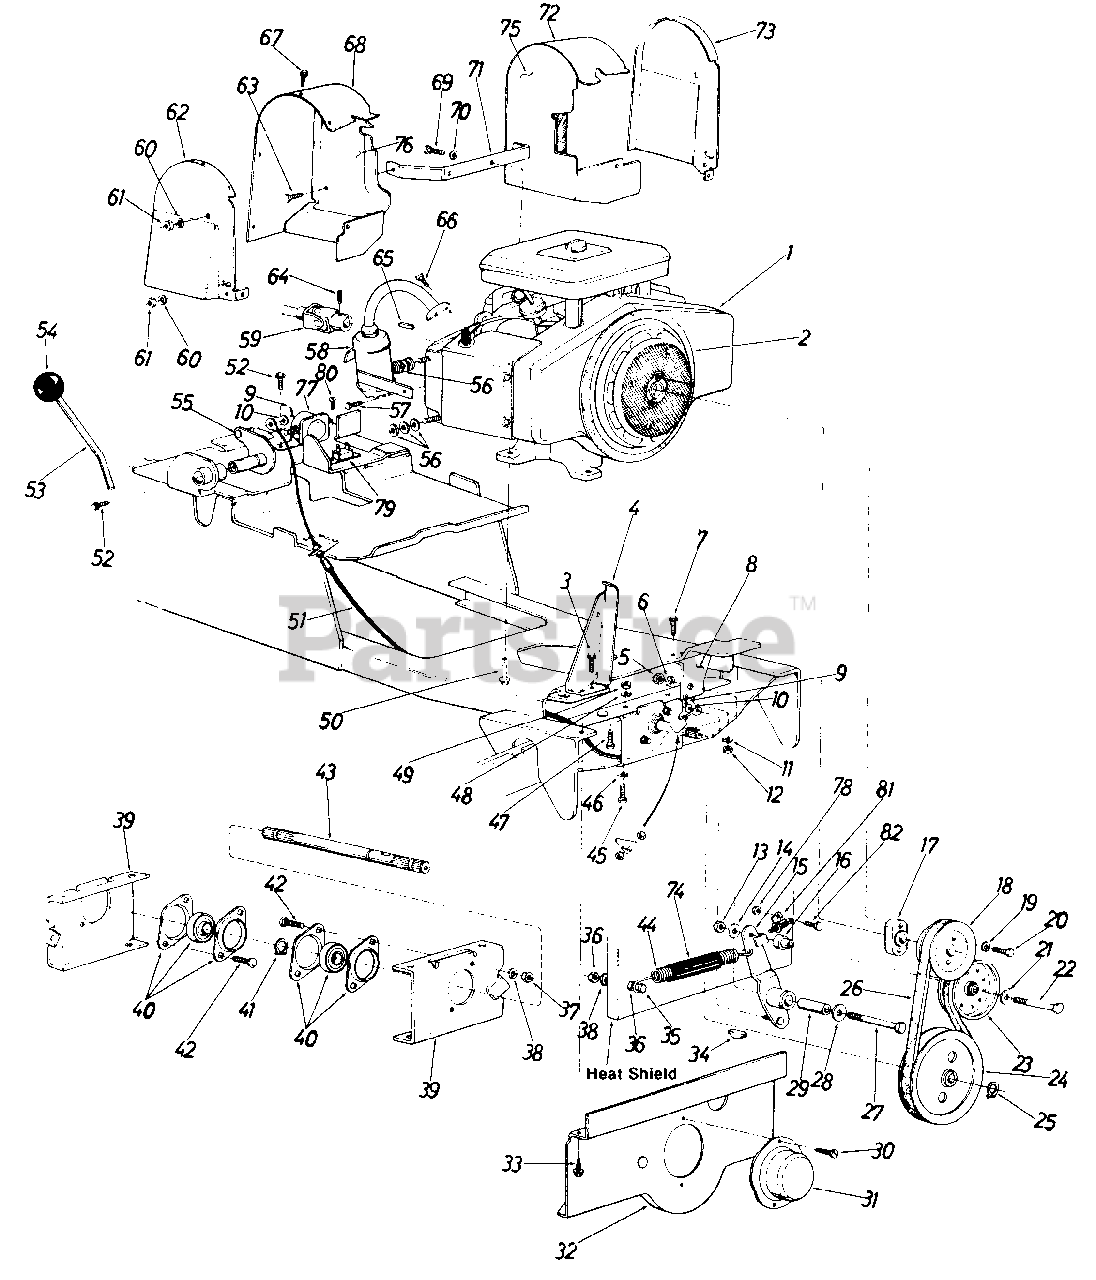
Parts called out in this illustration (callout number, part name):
1	Engine
2	Mylar Foam Strip
3	Hex Wash. Hd. Self-Tap Scr. 1/4-20 x .75" Lg.
6	L-Wash. 3/8" Scr.
7	Hex Wash. Hd. Self-Tap Scr. 5/16-18 x .75" Lg.
10	Fl-Wash 38 I.D. x 1.25 O.D. x .10 Tik.
11	L-Wash. 3/8" Scr.
12	Hex Nut 3/8-16 Thd.
13	Hex Nut 3/8-16 Thd.
14	Fl-Wash. .38 I.D. x 1.25" O.D. x .10 Thk.
17	Pulley Spacer
18	1/2" V-Pulley 4.75" O.D.
19	L-Wash. 3/8" Scr. H.D.
20	Hex Scr. 3/8-16 x 2.00" Lg.
21	Fl-Wash. .38" I.D. x 1.25 O.D x .010 Thk.
22	Hex Scr. 3/8-16 x 2.50" Lg.
23	Flat Idler Pulley
24	1/2" V-Pulley 7.00" O.D.
26	"V"-Belt 1/2" X 41" Lg.
27	Hex Scr. 3/8-16 x 2.50" Lg.
28	Fl-Wash. .38" I.D. x 1.25" O.D. x .010
29	Spacer .375" I.D. x .62" O.D. x 1.830 Lg.
30	Hex "B" Tap Scr. #10 x .50" Lg.
34	#91 Hi-Pro Key
35	Hex Scr. 5/16-18 x 1.25" Lg.
36	Hex Nut 5/16-18 Thd.
37	Hex Nut 5/16-18 Thd.
38	L-Wash. 5/16" Scr.
39	PTO Brg. Retainer Brkt.
40	1.00"Dia. Brg. w/ Flangette
42	Carr. Bolt 5/16-18 x .75" Lg.
43	Spline Shaft
44	Extension Spring
45	Hex Scr. 3/8-16 x 1.00" Lg.
46	L-Wash. 3/8" Scr.
47	Hex Scr. 3/8-16 x 1.00' Lg.
48	L-Wash. 3/8" Scr.
49	Hex Nut 3/8-16 Thd.*
50	Hex Wash. Hd. Self-Tap Scr. 3/8-16 x 1.25" Lg.
51	PTO Control Cable
52	Hex Wash. Hd. Self-Tap Scr. 1/4-20 x .50"
54	Ball Knob
55	PTO Actuator Lever Ass'y.
56	Fl-Wash. .312" I.D. x 1.620" O.D. x .060
57	Hex Wash. Hd. Self-Tap Scr. 1/4-20 x .50" Lg.
58	Muffler Ass'y. Comp. R. H .
59	Universal Joint Ass'y. Comp.
60	Fl-Wash. .312" I.D. x .630" O.D. x .063
61	Hex Nut 5/16-18 Thd.
62	Shroud Outer R.H.
63	Hex Wash. Hd. Self-Tap Scr. 1/4-20 x .50" Lg.
64	Sq. Hd. Set Scr. 5/16-18 x .38" Lg.
65	Sq. Key 1/4" x 2.00" Lg.
66	Hex Wash. Hd. Scr. 1/4-20 x 5/8" Lg. Grade 5
67	Hex 'AB" Tap Scr. #10 x .50" Lg.
68	Shroud Cover R.H.
69	Hex Scr. 5/16-24 x .75" Lg.
70	L-Wash. 5/16" Scr.
71	Shroud Support Brkt.
72	Shroud Cover L.H.
73	Shroud Outer L.H.
74	Spring Cover Tubing
75	Shroud Inner Ass'y. L.H.
76	Shroud Inner Ass'y. R.H.
77	Solenoid
78	Hex Scr. 1/4-20 x 1/2" Lg.
79	Circuit Breaker
80	Truss Mach. Scr. #10 x .50" Lg.
81	Safety Switch
82	L-Wash. 1/4" Scr.
13546-0648	CUP-PTO - TECH GRAY (0648)
